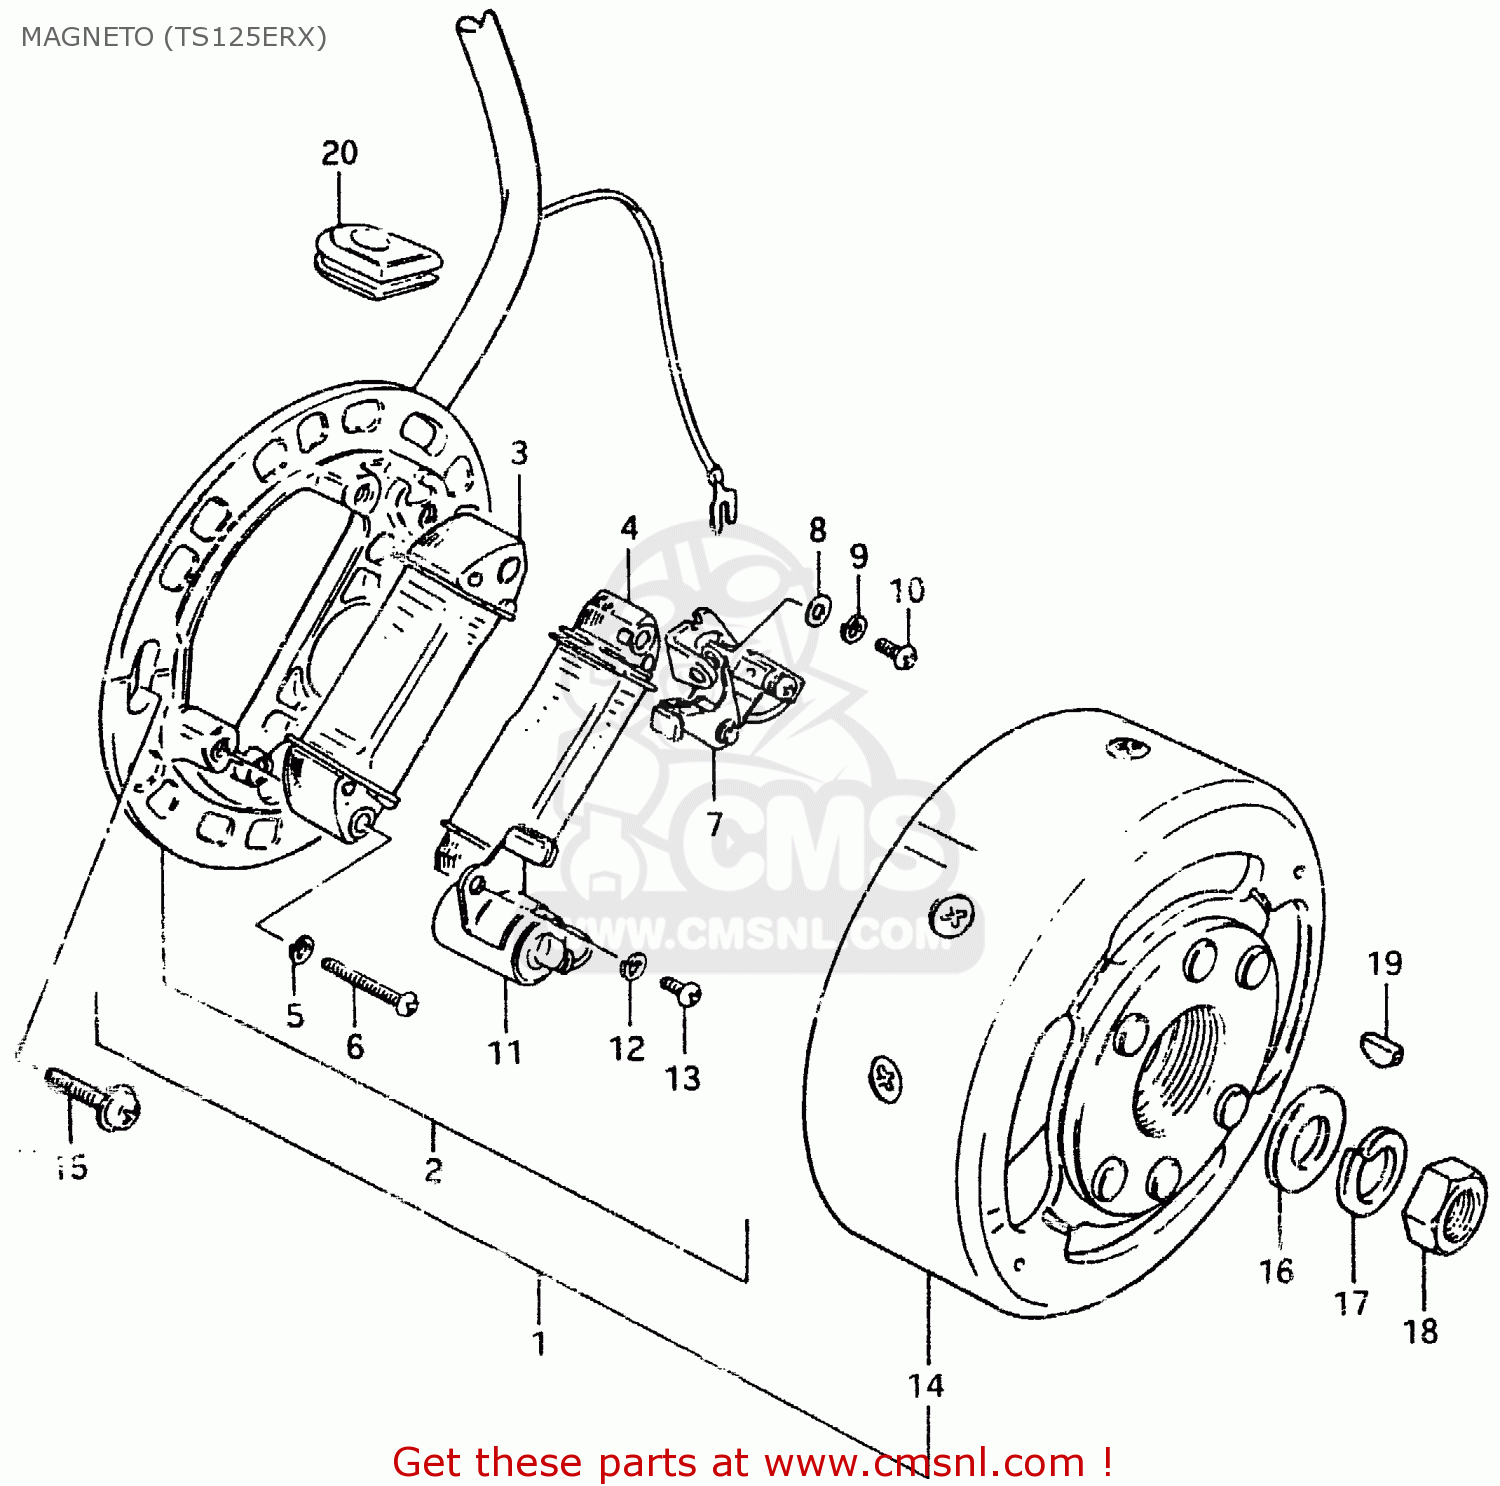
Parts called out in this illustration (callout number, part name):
1	MAGNETO ASSY
2	STARTER ASSY
3	COIL, LIGHTING
4	COIL,PRIMARY
5	LOCK WASHER
6	SCREW (4X30)
7	POINT ASSY,CONTACT
8	WASHER
9	LOCK WASHER
10	SCREW(4X10)
11	CONDENSER
12	LOCK WASHER
13	SCREW
14	ROTOR
15	SCREW(5X14)
16	WASHER
17	LOCK WASHER
18	NUT (10MM)
19	KEY
20	GROMMET
